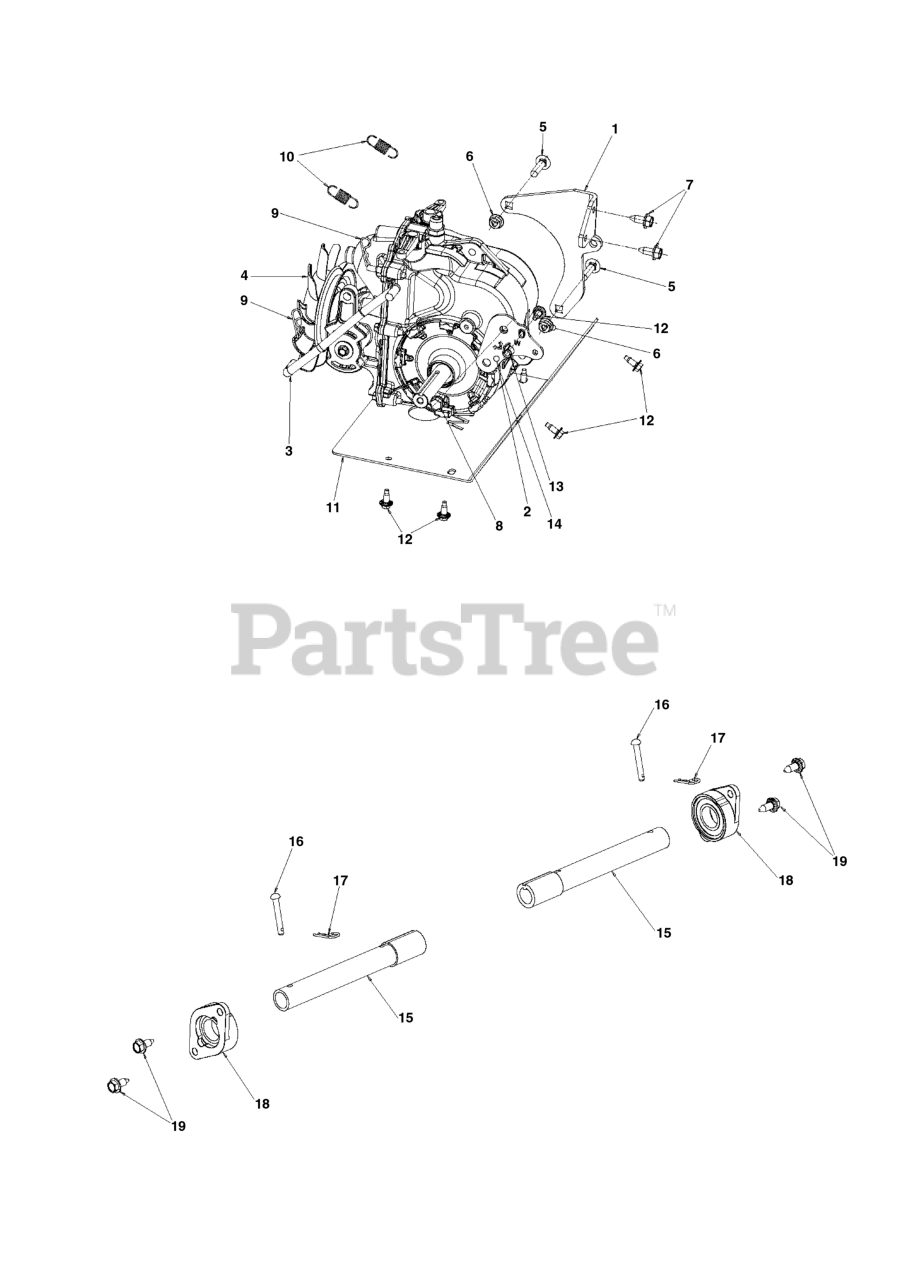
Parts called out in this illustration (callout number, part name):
2	Bell Cranks
4	TRANSMISSION HYDRAULIC POWER S
5	BOLT.CARRIAGE.5/16-18
6	NUT.LOCK.5/16-18
7	BOLT.HEX.HD.WASHER.5/16-18X.75
8	BOLT SHOULDER 3/8-20 X.25
9	SPRING RETAINER
10	SPRING IDLER RETURN
12	HEX.WASHER.HEAD 1/4-20 X .65
13	Nuts
13	WING NUT 1/4
14	WASHER
15	AXLE WHEEL
16	RIVET,DRILLED
17	RETAINER M
18	CARRIER BEARING
19	BOLT.HEX.HD.WASHER.5/16-18X.75
